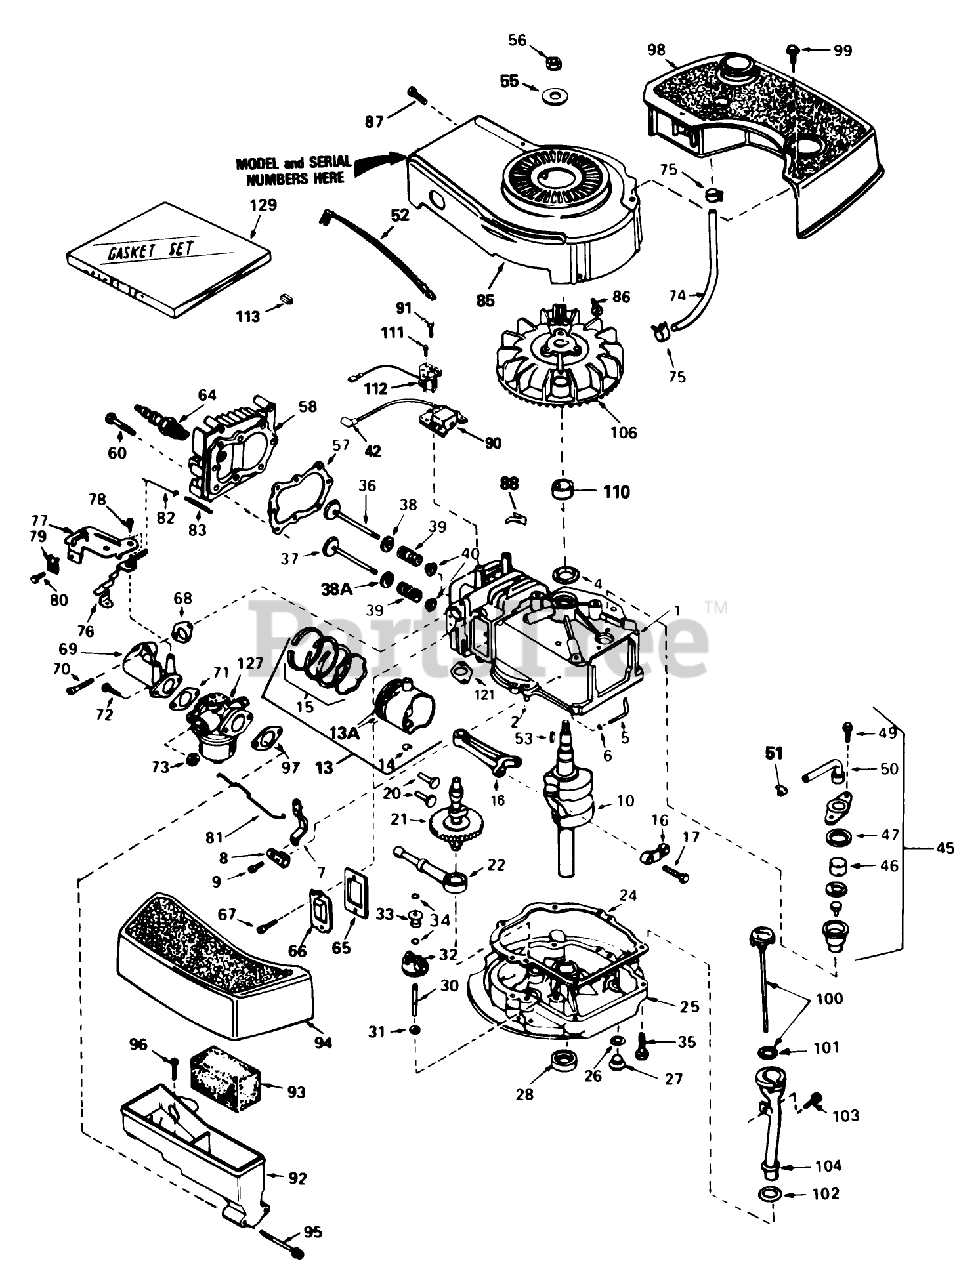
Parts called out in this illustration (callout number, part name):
1	Cylinder Assy. (Inc. #2 4)
2	Pin-Dowel
4	Seal-Oil
5	Rod, Governor (Incl. No. 36)
6	Washer-Flat
7	Governor Lever
8	Clamp-Lever, Governor
9	Screw
10	Crankshaft
13	Piston, Pin Ring Assy. (Std.) (Incl. Ref. #13A, 14 15)
13	Piston, Pin Ring Assy. (.010 oversize) (Incl. Ref. #13A, 14 15)
13	Piston, Pin Ring Assy. (.020 oversize) (Incl. Ref. #13A, 14 15)
13A	Piston Pin Assy. (Incl . Ref. . #14) (Std.)
13A	Piston Pin Assy. (Incl. Ref. #14) (.010 Oversize)
13A	Piston Pin Assy. (.020 oversize) (Incl. Ref. #14)
14	Ring-Retaining, Piston Pin
15	Ring Set (Std.)
15	Ring Set (.020" OS)
15	Ring Set (.010" OS)
16	Rod Assy., Connecting (Incl. Ref. #17)
17	OA Bolt-Connecting Rod
20	Lifter-Valve
21	Camshaft(Mech.Comp. Release)
22	Oil Pump ASM
24	Gasket
25	Flange Assy.-Mounting (Incl. Ref. #26, 27, 28 31)
26	Gasket-Oil Drain
27	Plug Oil Drain
28	Seal Oil
30	Shaft-Governor
31	Washer-Flat
32	Governor Gear ASM
33	Spool-Governor
34	Ring-Retaining
35	Screw (1/4-20 x 1-1/4)
36	Valve, Intake (Std.) (Incl. Ref. #40)
36	Valve, Intake (1/32" oversize)(Incl. No. 40)
37	Valve, Exhaust (Std.)(Incl. No. 40)
37	Valve, Intake (1/32" oversize)(Incl. No. 40)
38	Seal Assy., Intake
38A	Cap-Upper Valve Spring
39	Spring-Valve
40	Cap-Valve, Spring
42	Cover-Spark Plug
45	Breather Assy. (Incl. Ref. #46 thru 51)
46	Element-Breather
47	Gasket-Breather
49	Screw (10-24 x 9/16)
50	Tube, Breaker
51	Clip, Breather
52	Wire-Ground
53	Key-Flywheel
55	Washer-Belleville
56	Nut-Flywheel
57	63573 GIL 42 SNWTHW
58	Head-Cylinder
60	Screw (5/16-18x1-1/2)
64	Plug, Spark (Autolite 458, Champion J-19LM or equiv.)
65	Gasket-Breather
66	Cover-Valve
67	Screw
68	Gasket-Intake
69	Pipe, Intake (Incl. No. 68)
70	Screw (1/4-20 x 1)
71	Gasket-Carburetor
73	Nut and Lock Washer (1/4-28)
74	Line-Fuel
75	Clamp-Line, Fuel
76	Lever Control
77	Control Assy., Speed (Incl. Nos, 76, 78 89)
78	Screw, Hex Washer Hd Shoulder Self-Tap
79	Conduit
80	Screw (10-32 x 3/8)
81	Link-Throttle
82	Link Governor Spring
83	Spring Governor
85	Housing-Blower
86	Screw (1/4-20x19/32)
87	Screw (10-24 x 9/16)
88	Clip-Wire
90	Solid State
91	Screw
92	Body Air Cleaner
93	Filer, Air
94	Cove, Air Cleaner
95	Screw Fil Hd.
96	Screw, Hex Washer Hd Shoulder Self-Tap
97	Gasket-Air Cleaner
98	Tank-Fuel
99	Screw (10-32 x 35/64)
100	Dipstick, Oil (Incl. Ref. #101)(Twist Lock)
101	O-Ring
102	Gasket
103	Screw (10-32 x 1/2)
104	Tube-Oil Fill
106	Flywheel
110	Spacer
111	Screw (8-32x27/64)
112	Coil, Alternator
113	Connector-Body
121	Gasket Exhaust
127	Carburetor (Incl. Ref. #71)
129	Gasket Set
